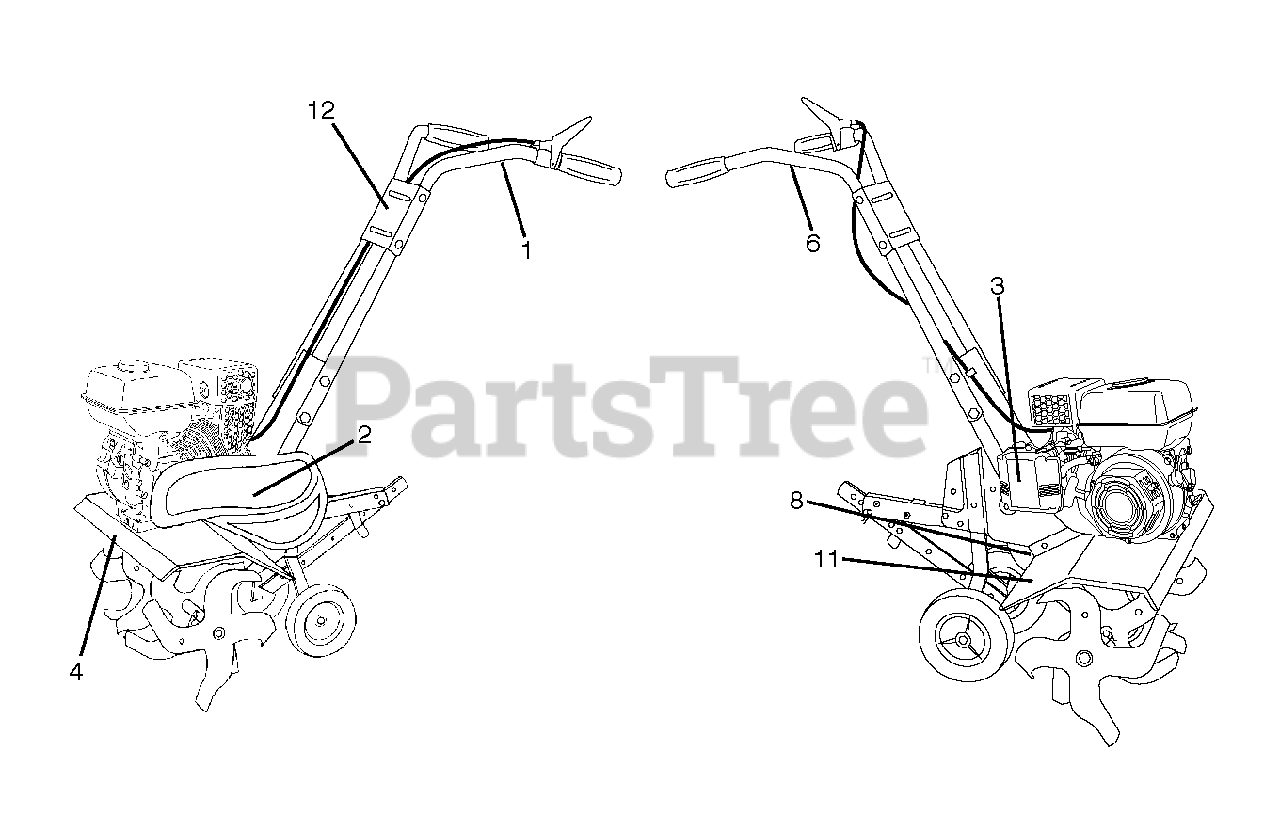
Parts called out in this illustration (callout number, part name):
1	DECAL.TINE.CONTROL.ENG/FR
4	DECAL.TINE.SHIELD.HD.YELLOW.PP
6	DECAL TI
11	DECAL WARNING
12	DECAL.CONSOLE.TILLER.YELLOW.PP
